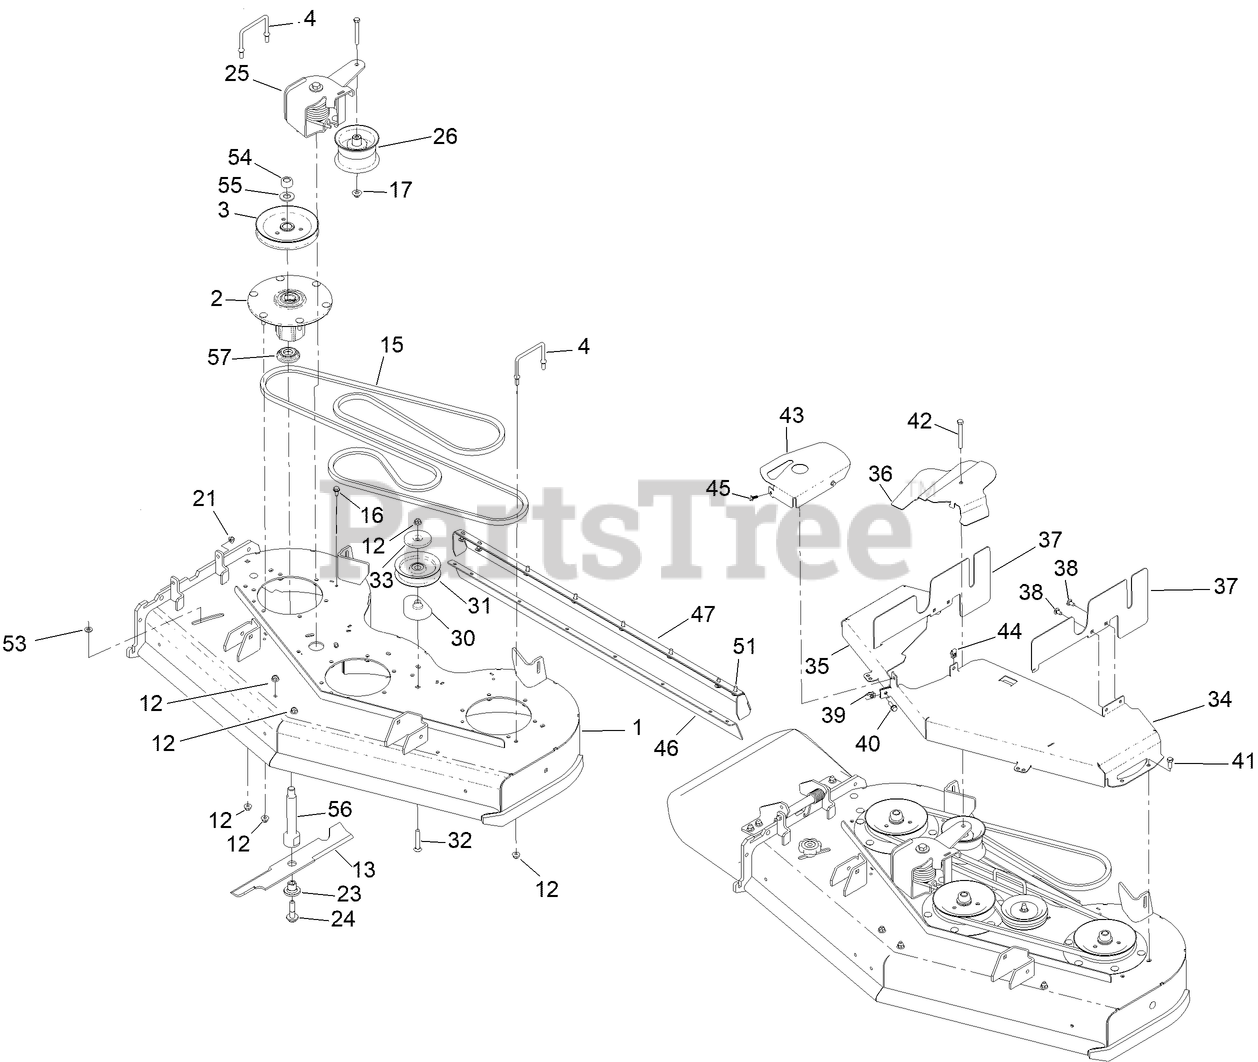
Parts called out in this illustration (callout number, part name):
1	DECK AND DECAL ASM
2	SPINDLE ASM
3	SHEAVE-BLADE, DRIVE
4	WIREFORM-COVER
12	NUT-HF, NI
13	BLADE-16.50 ATOMIC
15	BELT-V
16	SCREW-HWHTF
17	NUT-FLANGE, NI
21	NUT-HF, NI
23	BUSHING-HEX
24	SCREW-SEMS
25	IDLER TORSION ASM
26	PULLEY-IDLER
30	SPACER-PULLEY
31	PULLEY-IDLER, FLAT
32	SCREW-CARR
33	SHIELD-DUST
34	COVER-BELT, LH, CE
35	COVER-BELT, RH CE
36	COVER-IDLER, CE
37	COVER-SIDE, LH (CE)
38	SCREW-CARR
39	NUT-U
40	SCREW-HHF
41	SCREW-HH
42	SCREW-HH
43	COVER-IDLER, CE
45	SCREW-HHF
46	DEFLECTOR
47	BRACKET-DEFLECTOR
51	BOLT-CARR
53	WASHER-HARDENED
54	NUT-HEX
55	WASHER
56	SHAFT-SPINDLE
57	GUARD-BOTTOM
